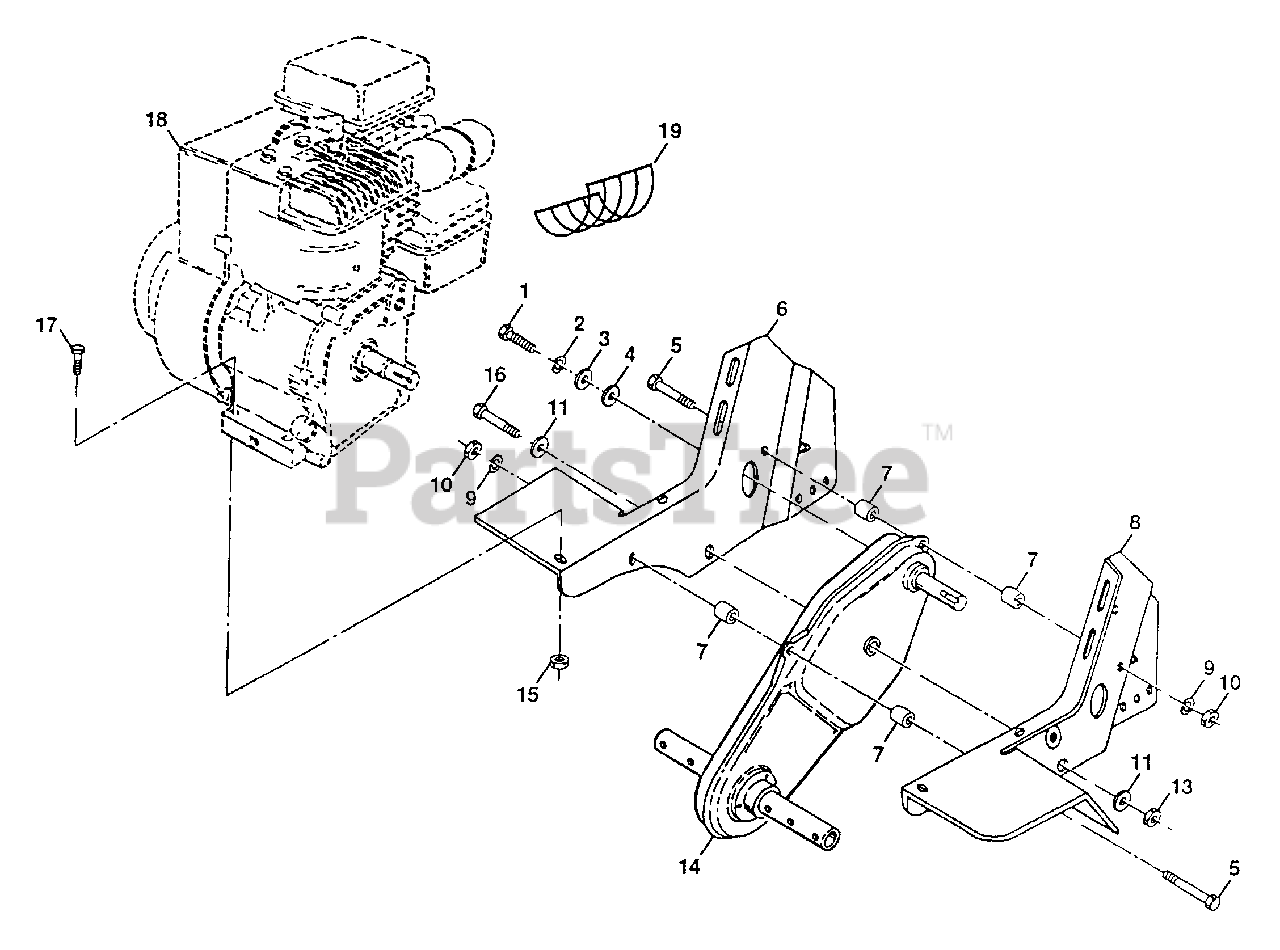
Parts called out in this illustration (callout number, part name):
1	Bolt, Hex 1/4-28 x 3/4 Gr. 5
2	Washer, Lock 1/4
3	Washer 9/32 x 1-1/4 x 16 Ga.
4	Washer 9/32 x 7/8 x 12 Ga.
5	Bolt, Hex 5/16-18 x 2-3/4 (AYP part number)
6	Bracket, Engine, R.H.
7	Spacer, Split
8	Bracket, Engine, L.H.
9	Washer, Lock 5/16
10	Nut, Hex 5/16-18
11	Washer 13/32 x 13/16 x 11 Ga.
13	Locknut, w/Insert 3/8-16
14	Transmission
15	Nut, Keps 5/16-18
16	Bolt, Hex 3/8-16 x 3-1/4
17	Bolt, Hex 5/16-18 x 1-1/2
18	Engine, Briggs & Stratton
